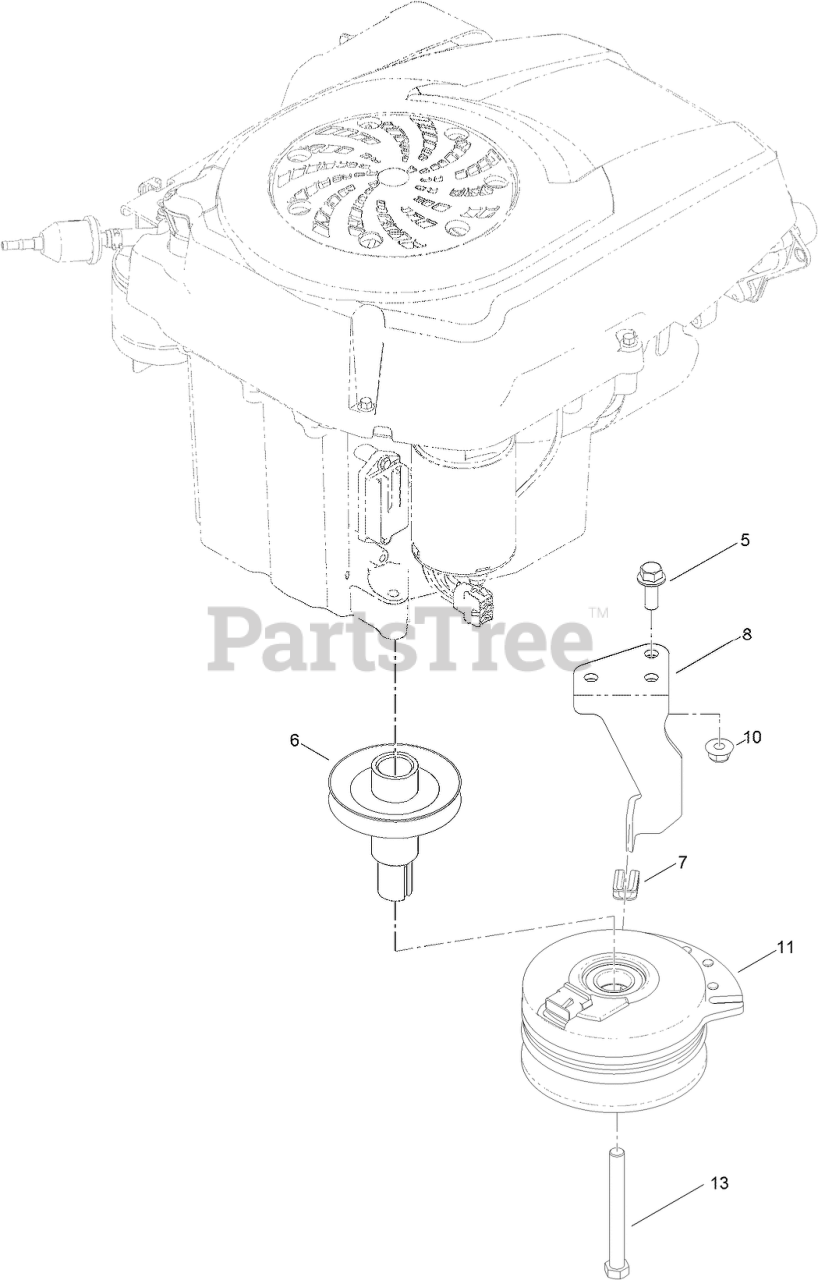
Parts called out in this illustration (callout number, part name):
5	SCREW-HHF
6	PULLEY-ENGINE
7	ISOLATOR-CLUTCH
8	STOP-CLUTCH
10	NUT-HF, NI
11	CLUTCH-ELECTRIC
13	SCREW-HH
